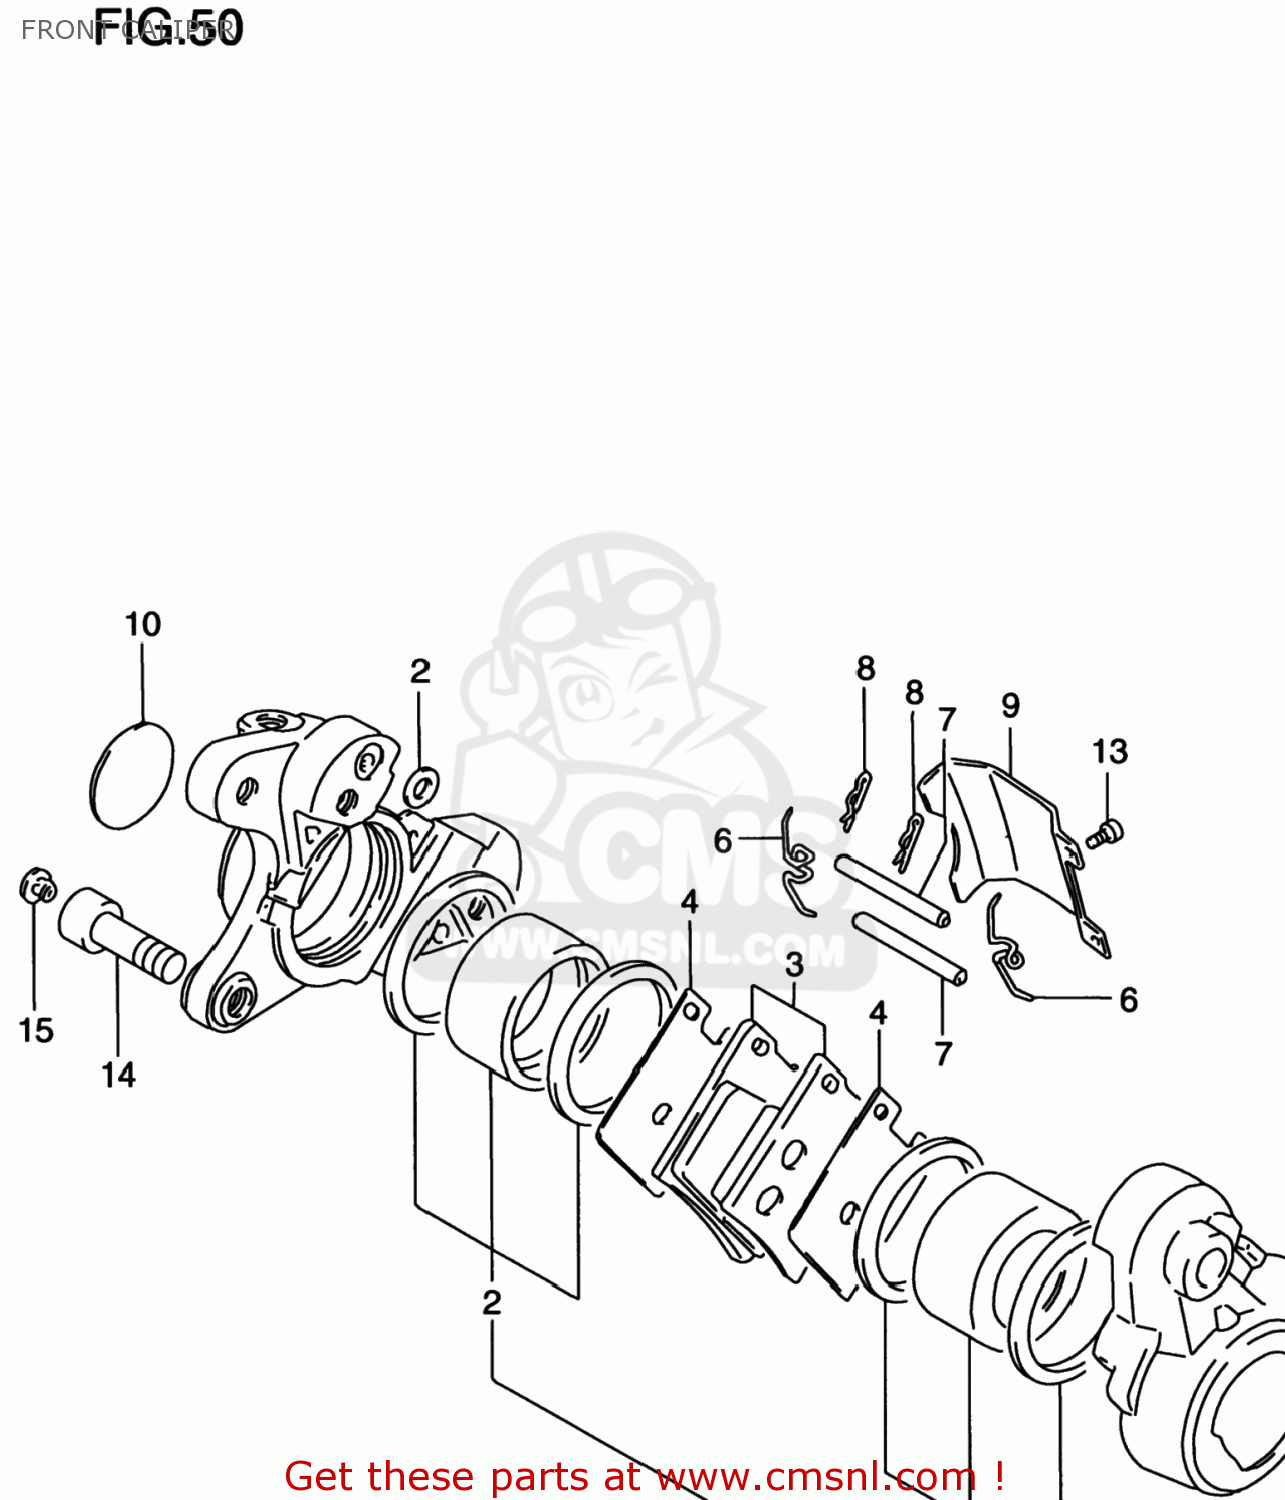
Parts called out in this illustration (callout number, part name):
1	PISTON SET
2	SEAL SET,PISTON
3	PAD SET (NAS)
4	SHIM,PAD
5	BOLT,HOUSING
6	SPRING
7	PIN,PAD
8	CLIP,PAD PIN
9	COVER,CALIPER HOUSING,DUST
10	CAP,CALIPER
11	BLEEDER
12	CAP,BLEEDER PLUG
13	SCREW,CALIPER COVER(4X6)
14	BOLT(10X33)
15	CAP(OD:12)
